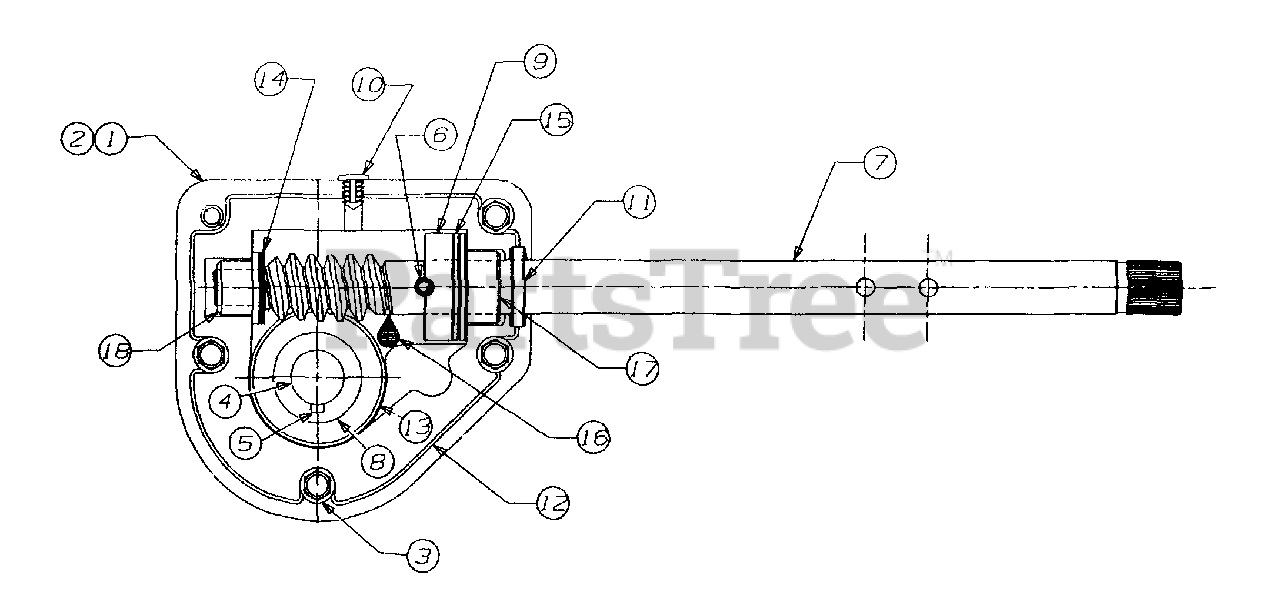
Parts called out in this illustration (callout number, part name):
1	Housing - R.H.
2	Housing - L.H.
3	Screw
4	Axle, Spiral 24"
4	Axle, Spiral 22"
5	Key, Hi-Pro
6	Pin, Spiral
7	Worm, Shaft
8	Gear, Worm
9	Collar, Thrust
11	Seal, Oil
12	Loctite 5699
13	Washer - Flat
14	Washer - Flat
15	Washer - Flat
16	Grease
17	Bearing Flange
18	Bearing Flange
